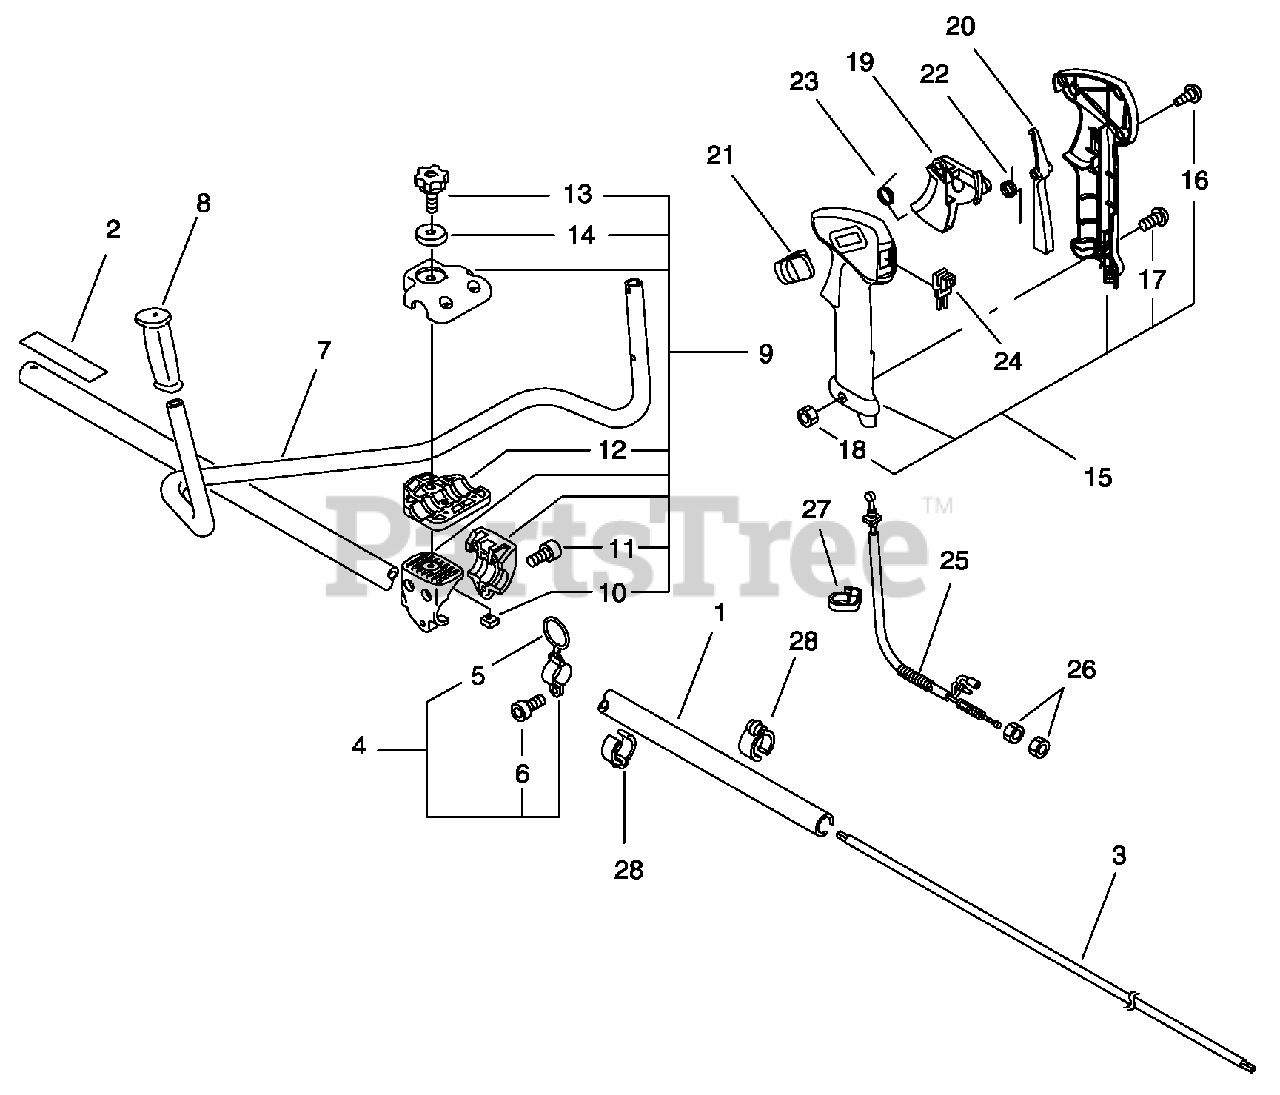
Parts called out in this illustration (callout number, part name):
1	MAIN PIPE ASSY
2	LABEL, CAUTION - ISO
3	DRIVESHAFT
4	HANGER SET, HARNESS
5	RING, HARNESS
6	BOLT 5×12
7	HANDLEBAR
8	GRIP, HANDLE
9	DEBRIS SHIELD ASSY
10	NUT 8×1.25
11	BOLT 5×30
12	MOUNT, HANDLE
13	KNOB, SCREW M8
14	WASHER 8
15	THROTTLE CONTROL ASSY
16	SCREW 4×16
18	NUT M5
19	TRIGGER, THROTTLE
20	LOCKOUT, THROTTLE
22	SPRING, TORSION
23	SPRING, TORSION
24	SWITCH ASSY, ON-OFF
25	CABLE, THROTTLE
28	CLIP, CABLE 25 MM
